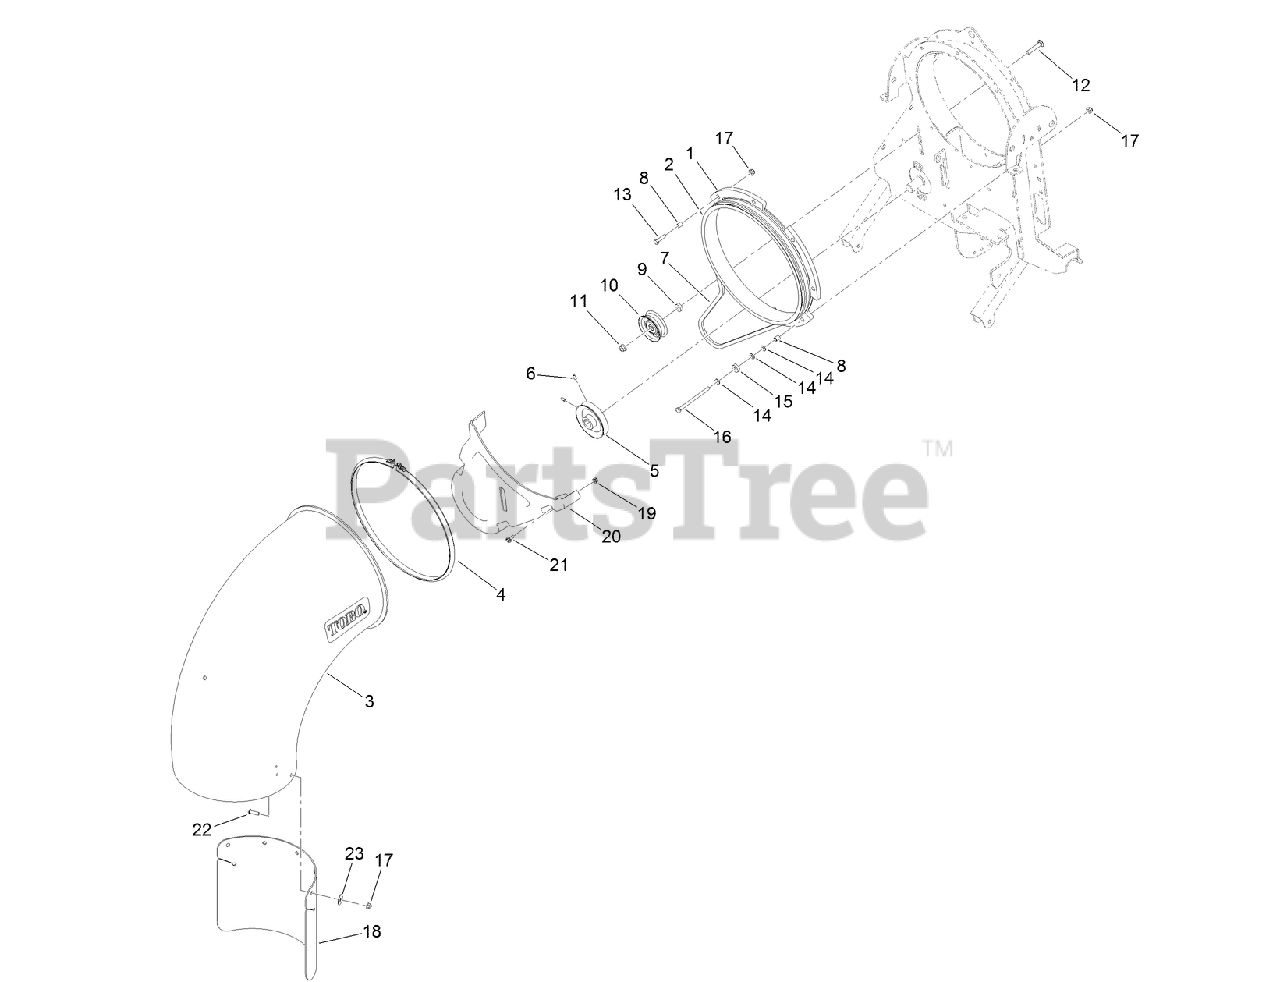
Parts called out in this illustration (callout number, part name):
1	GUIDE-NOZZLE
2	PULLEY-NOZZLE
3	NOZZLE
4	CLAMP-NOZZLE
5	PULLEY
6	SCREW-SET, HSH
7	BELT-V
8	SPACER
9	SPACER
10	PULLEY-IDLER, FLAT
11	NUT-HF, NI
12	BOLT-CARRIAGE
13	SCREW-HH
14	WASHER-FLAT
15	BEARING-BALL
16	SCREW-HH
17	NUT-HF, NI
18	EXTENSION-NOZZLE
19	NUT-CLIP
20	COVER-BELT
21	SCREW-HWH
22	SCREW-HSBH
23	WASHER-FLAT
